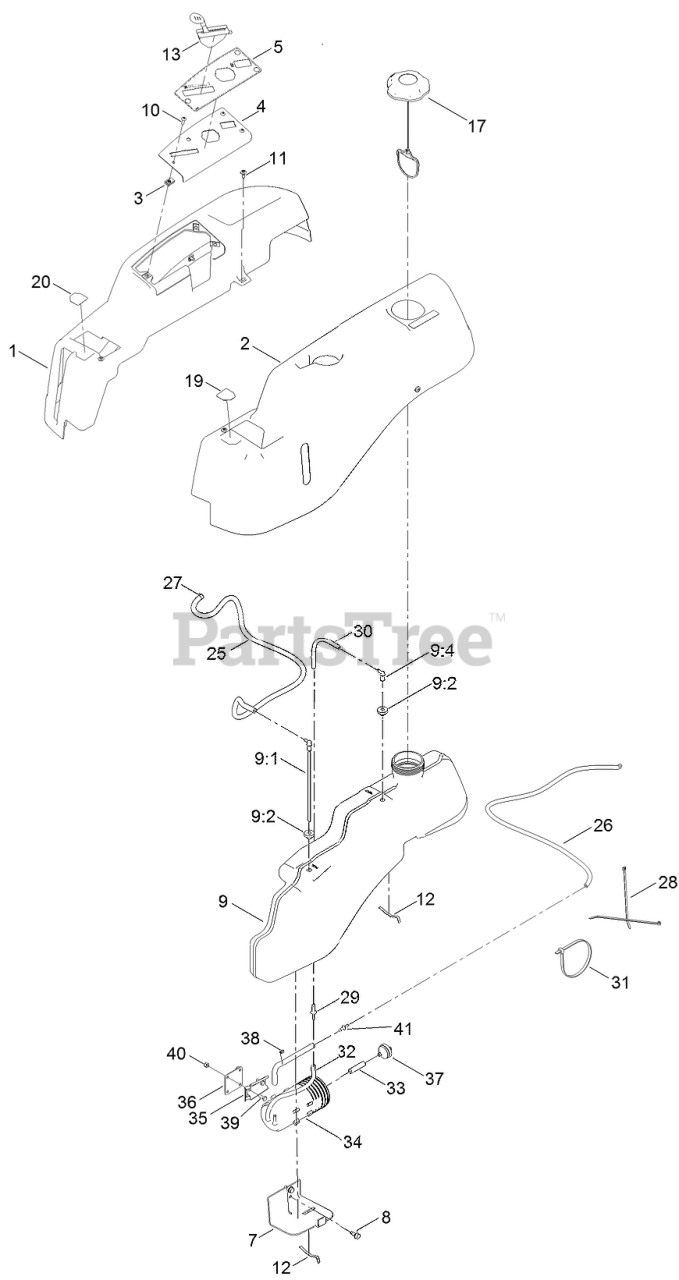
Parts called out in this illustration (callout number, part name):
1	POD-RH
2	POD-LH
4	PLATE-CONTROL
5	DECAL-PANEL, CONTROL
7	SUPPORT-TANK, FRONT
8	SCREW-HWHTF
9	FUEL TANK ASM
9:1	CONNECTOR-ELBOW, 90 DEG
9:2	BUSHING
9:4	FITTING-PLASTIC
10	SCREW-PRH
11	SCREW-SHOULDER
12	SPRING
13	CABLE-THROTTLE AND CHOKE
17	CAP-FUEL, RATCHETING
19	DECAL-LEVER, CONTROL (LH)
20	DECAL-LEVER, CONTROL (RH)
25	HOSE-FUEL
26	HOSE-FUEL
27	CLAMP-HOSE
28	TIE-CABLE
29	ADAPTOR-ORIFICE
30	HOSE-FUEL
31	TIE-CABLE
32	HOSE-FUEL
33	HOSE-FUEL
34	CANISTER-CARBON, 800CC
35	BRACKET-CANISTER, CARBON
36	PLATE-ADAPTER
37	FILTER-FUEL, INLINE
38	CARTRIDGE-VALVE, CHECK
39	SCREW-HH
40	NUT-LOCK, NI
41	FITTING-STRAIGHT
